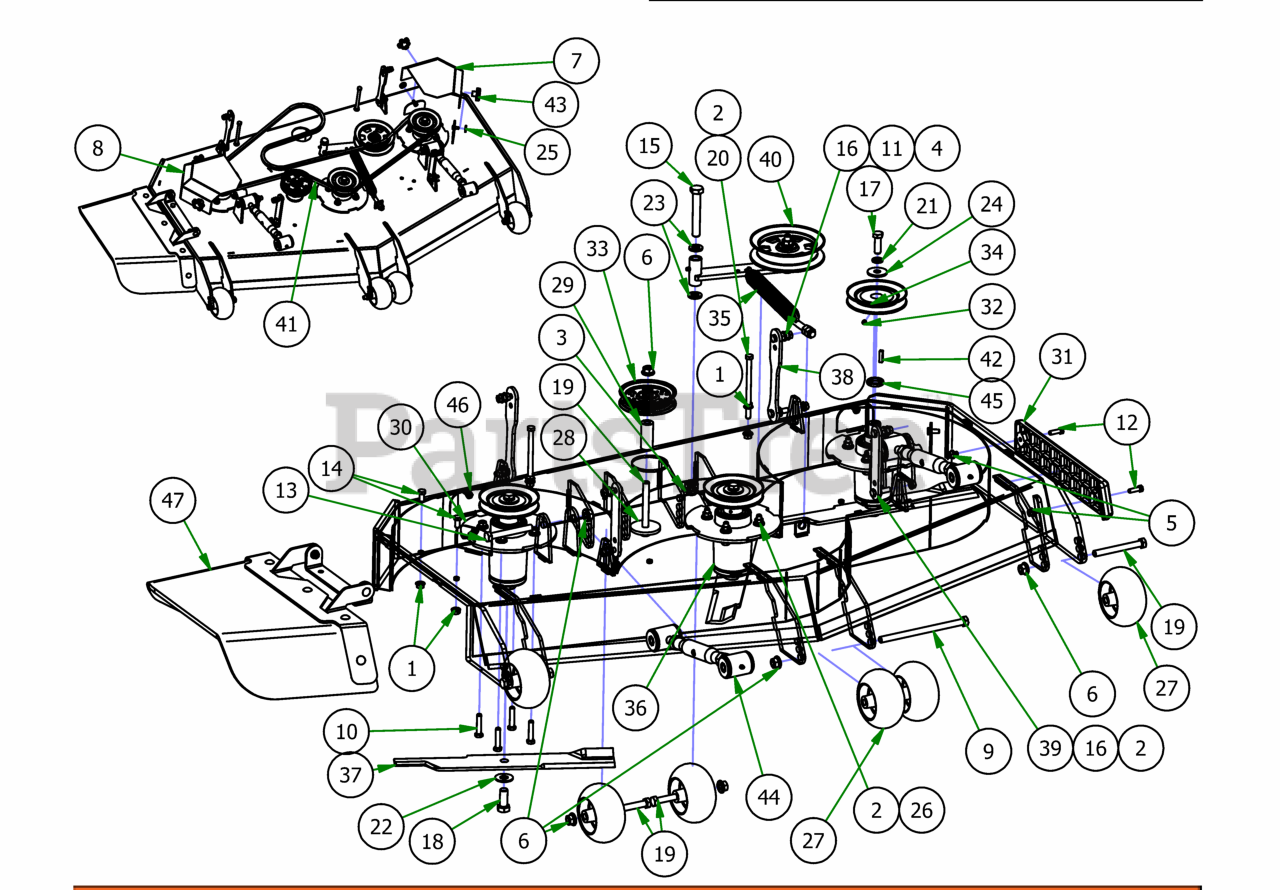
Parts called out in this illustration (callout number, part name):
1	3/8-16 HEX SERRATED FLANGE NUT HARD/ZINC
2	3/8-16 NYLON INSERT FLANGE LOCKNUT (GR.F) ZINC
3	5/8-11 NYLON INSERT JAM LOCKNUT ZINC
4	1/2-13 HEX NUT ZINC
5	5/16-18 NYLON INSERT FLANGE LOCKNUT ZINC
6	1/2-13 NYLON INSERT FLANGE LOCKNUT ZINC
7	2019 Stand On 54" Pulley Cover Trim
8	2019 Stand On 54" Pulley Cover Discharge
9	1/2-13 X 8 HEX CAP SCREW GR 5 ZINC
10	3/8-16 X 1-3/4 HEX C/S (GR.5) ZC
11	All Thread
12	5/16-18 X 1 HEX CAP SCREW (GR.5) ZINC
13	1/2-13 X 4 HEX CAP SCREW (GR.8) ZINC YELLOW
14	3/8-16 X 3/4 HEX CAP SCREW (GR.5) ZINC
15	5/8-11 X 4 HEX CAP SCREW (GR.8) ZINC YELLOW
16	3/8 x 1 1/2 Bolt
17	1/2-20 X 1-1/2 HEX CAP SCREW (GR.5) ZINC
18	5/8-18 X 1-1/2 HEX CAP SCREW (GR.8) ZINC YELLOW
19	1/2-13 X 4-1/2 HEX CAP SCREW (GR.5) ZINC
20	3/8-16 X 5-1/2 HEX CAP SCREW (GR.5) ZINC
21	1/2 SPLIT LOCKWASHER (GR.8) ZINC/YELLOW
22	5/8 USS FLAT WASHER (1-3/4" OD) GR.8 ZINC YELLOW
23	.635 ID X 1.120 OD X .140 THICK FLAT WASHER NYLON
24	1/2 BELLEVILLE WASHER (1-5/8 OD X .140 THK) ZINC
25	.360 ID X .983 OD X .120 THICK FLAT WASHER NYLON BLACK
26	5/16 USS FLAT WASHER (7/8 OD) ZINC
27	2019 Deck Wheel
28	MZ Deck Idler Spacer
29	2019 Revolt Stationary Idle Spacer
30	Deck Spindle Support Plate
31	REVISED TRIM BUMPER_20180226
32	5/16-24 X 1/4 SOCKET SET SCREW (CUP PT) PLAIN
33	4 3/4 Idler Pulley - ABFI-76
34	5" Spindle Deck Pulley
35	2019 Outlaw Gen2 Deck Spring
36	Spindle Assembly
37	54" Fusion Blade for ZT/Mav/Outlaw/Revolt
38	2019 Stand-On Rear Deck Hanger
39	2019 Revolt Front Deck Hanger
40	2019 Revolt Deck Idler Assembly
41	42 inch Deck Belt- B120
42	1/4 X 1 SQ MACHINERY KEY 1018 STL PLN
43	5/16" Knob
44	Turnbuckle
45	Spacer, 1x1.375x.25
46	2019 Stand On 54" Sloped Deck Welded Assemly
47	2019 Outlaw Gen2 Chute Assembly
